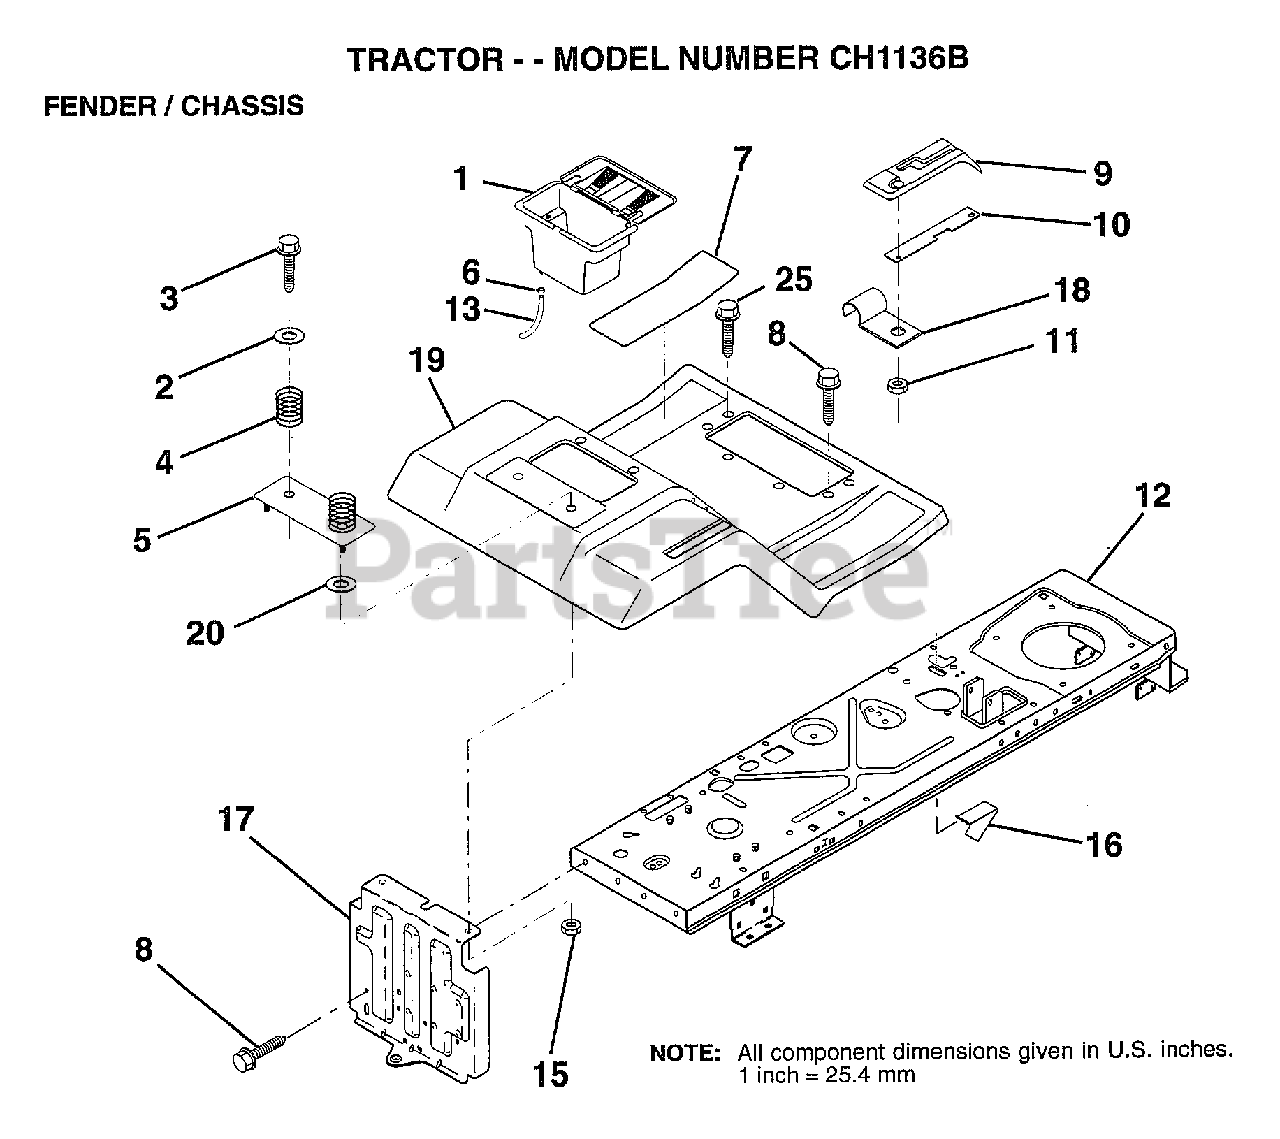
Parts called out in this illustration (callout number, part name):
2	WASHER
3	SCREW
4	SPRING COMPRESSIO
5	PLATE.FENDER.PNT
6	HOSE CLAMP T
7	PAD FOOTREST
8	SCREW
9	CONSOLE SHFT 4SP
10	PLATE LOCK SHIFT
11	NUT
12	CHASSIS.WELD.ASM.
13	TUBE T
14	NUT
15	NUT HXKEP 1/4X20
17	DRAWBAR ASM LR
18	"CLIP,INSULATOR"
19	FENDER/FOOTREST
25	SCREW
